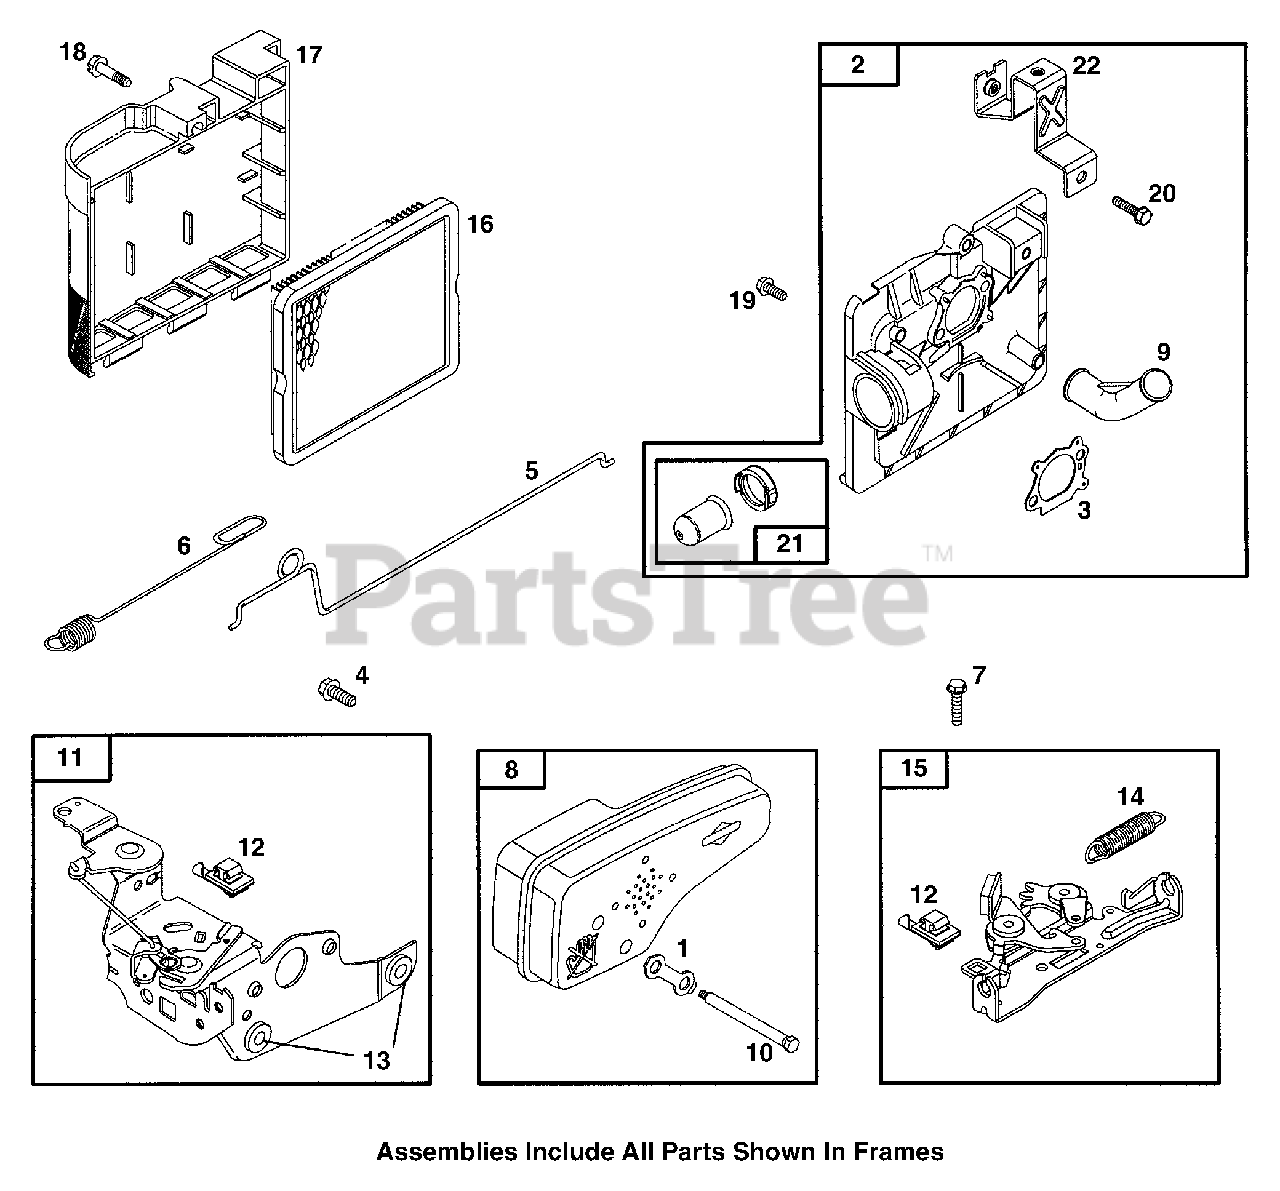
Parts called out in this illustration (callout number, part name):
1	Muffler Screw Lock
2	Air Cleaner Base
3	A/C Primer Gasket
4	Hex Screw
5	Mechanical Governor Link
6	Governor Spring
7	Slotted Hex Screw
8	Exhaust Muffler
9	Grommet
10	Shoulder Screw
11	Control Bracket
12	Stop Switch
13	Spacer
14	Brake Spring
15	Brake
16	A/C Cartridge Filter
17	Air Cleaner Cover
18	Slotted Hex Screw
19	Hex Screw
20	Hex Screw
21	Carburetor Primer
22	Air Cleaner Support
